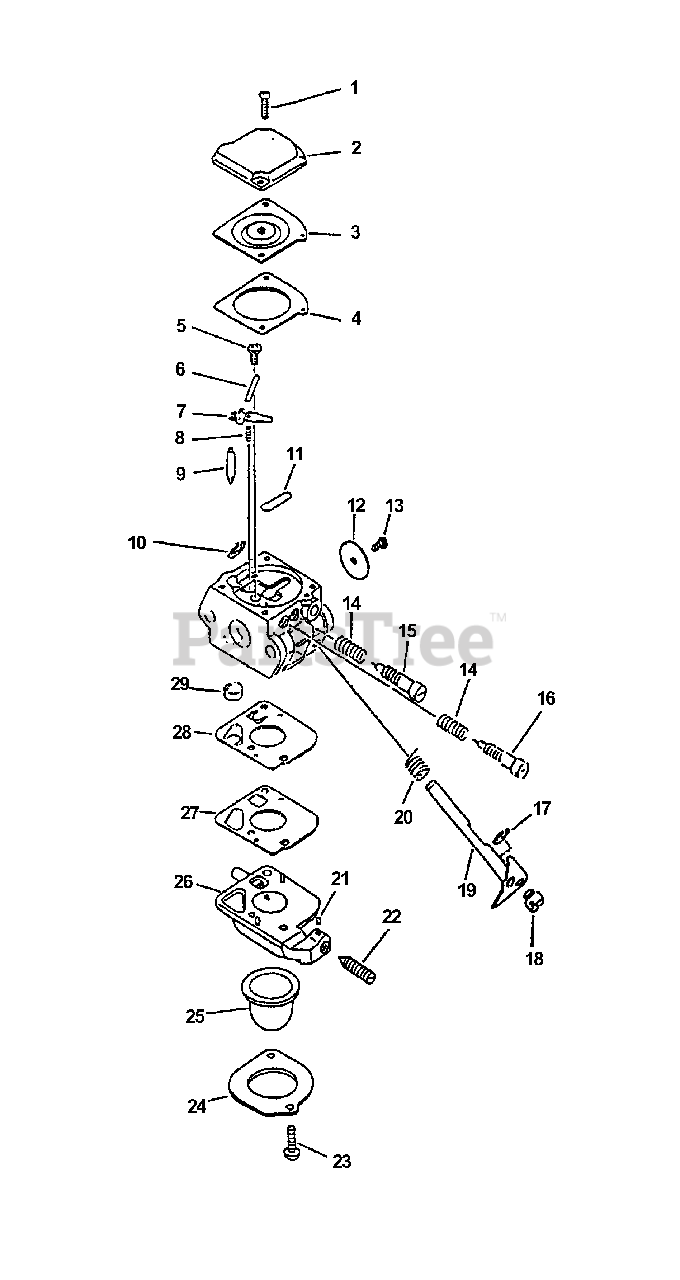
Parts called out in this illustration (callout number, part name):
2	COVER, METERING
3	DIAPHRAGM, METERING
4	GASKET, METERING
5	SCREW, METERING LEVER PIN
6	PIN, METERING LEVER
7	LEVER, METERING
8	SPRING, METERING LEVER
9	VALVE, INLET NEEDLE
10	RING, RETAINING
11	PLUG, WELCH
12	VALVE, THROTTLE
15	NEEDLE - LOW SPEED
16	NEEDLE - MIXTURE
17	RING, RETAINING
19	SHAFT, THROTTLE
20	SPRING, RETURN
21	PIECE, FRICTION
22	SCREW, IDLE ADJUST
24	RETAINER, PURGE BULB
25	BULB, PURGE
26	BASE, PURGE
27	GASKET, PURGE
28	DIAPHRAGM, PURGE
29	STRAINER
